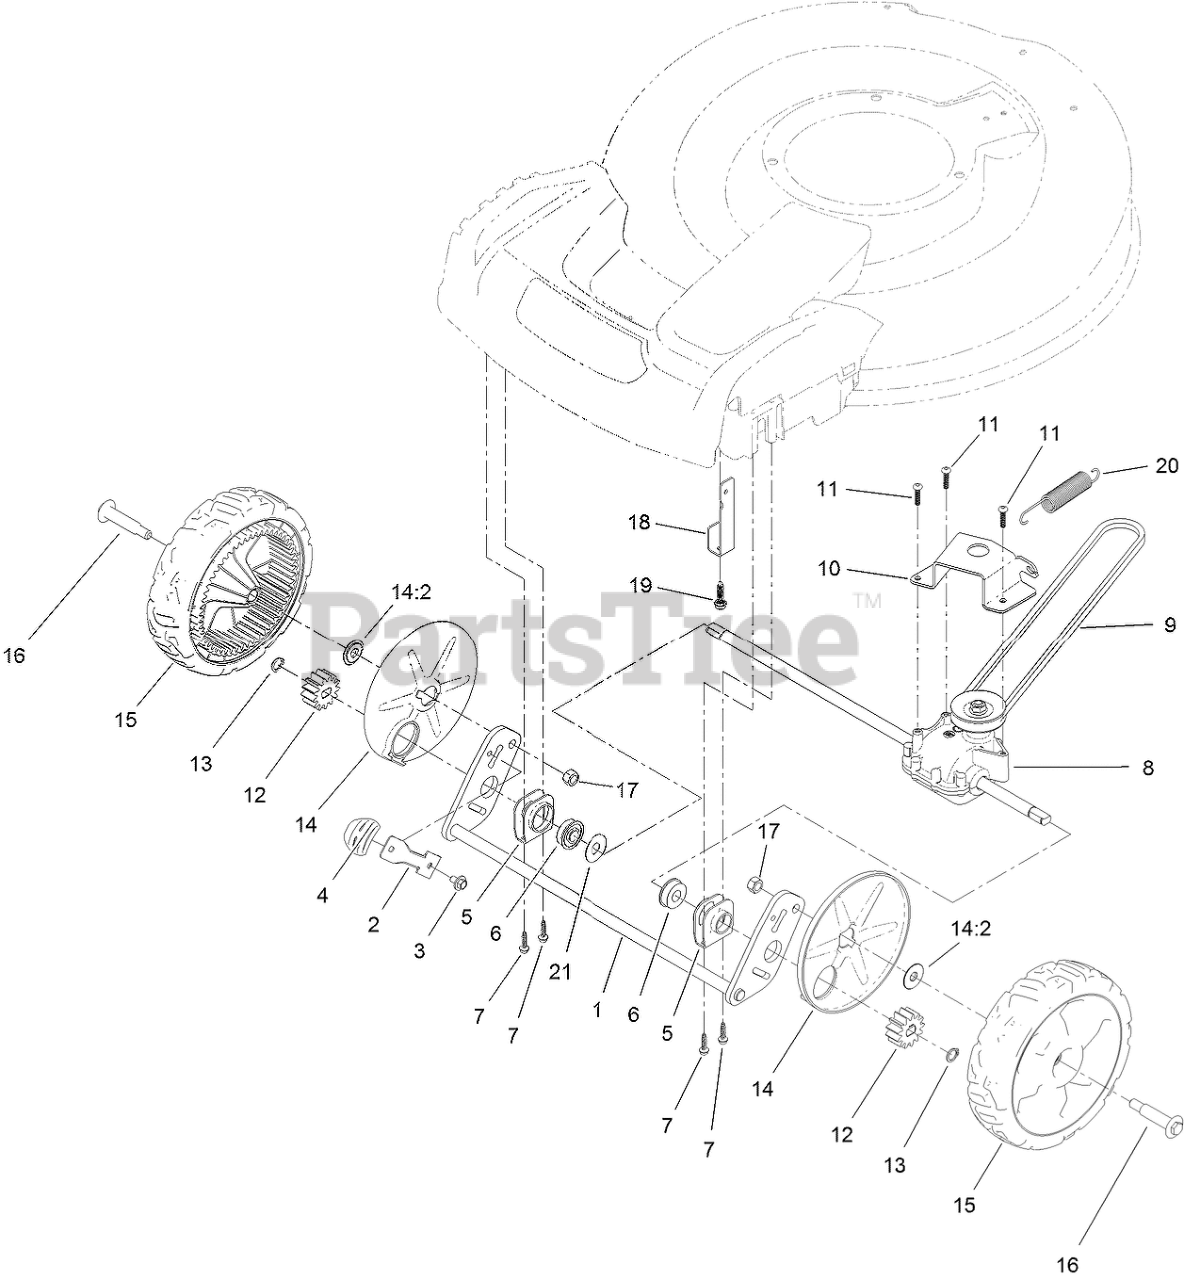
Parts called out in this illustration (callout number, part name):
1	AXLE-FRONT
2	ARM-SPRING
3	SCREW AND WASHER ASM
4	KNOB-LEVER, HOC
5	RETAINER-BEARING
6	BEARING-BALL
7	SCREW-HWH
8	TRANSMISSION
9	BELT-V
10	BRACKET-TRANSMISSION
11	SCREW-PLASTITE
12	GEAR-PINION, 13T
13	RING-RETAINING
14	WHEEL COVER ASM
14:2	WASHER-STEPPED
15	8 INCH WHEEL ASM (FRONT, WHITE)
16	BOLT-SHOULDER
17	NUT-HEX
18	BRACKET-ANCHOR, CABLE
19	SCREW-FLANGE, PLASTIC
20	SPRING-EXTENSION
21	WASHER-PLAIN
